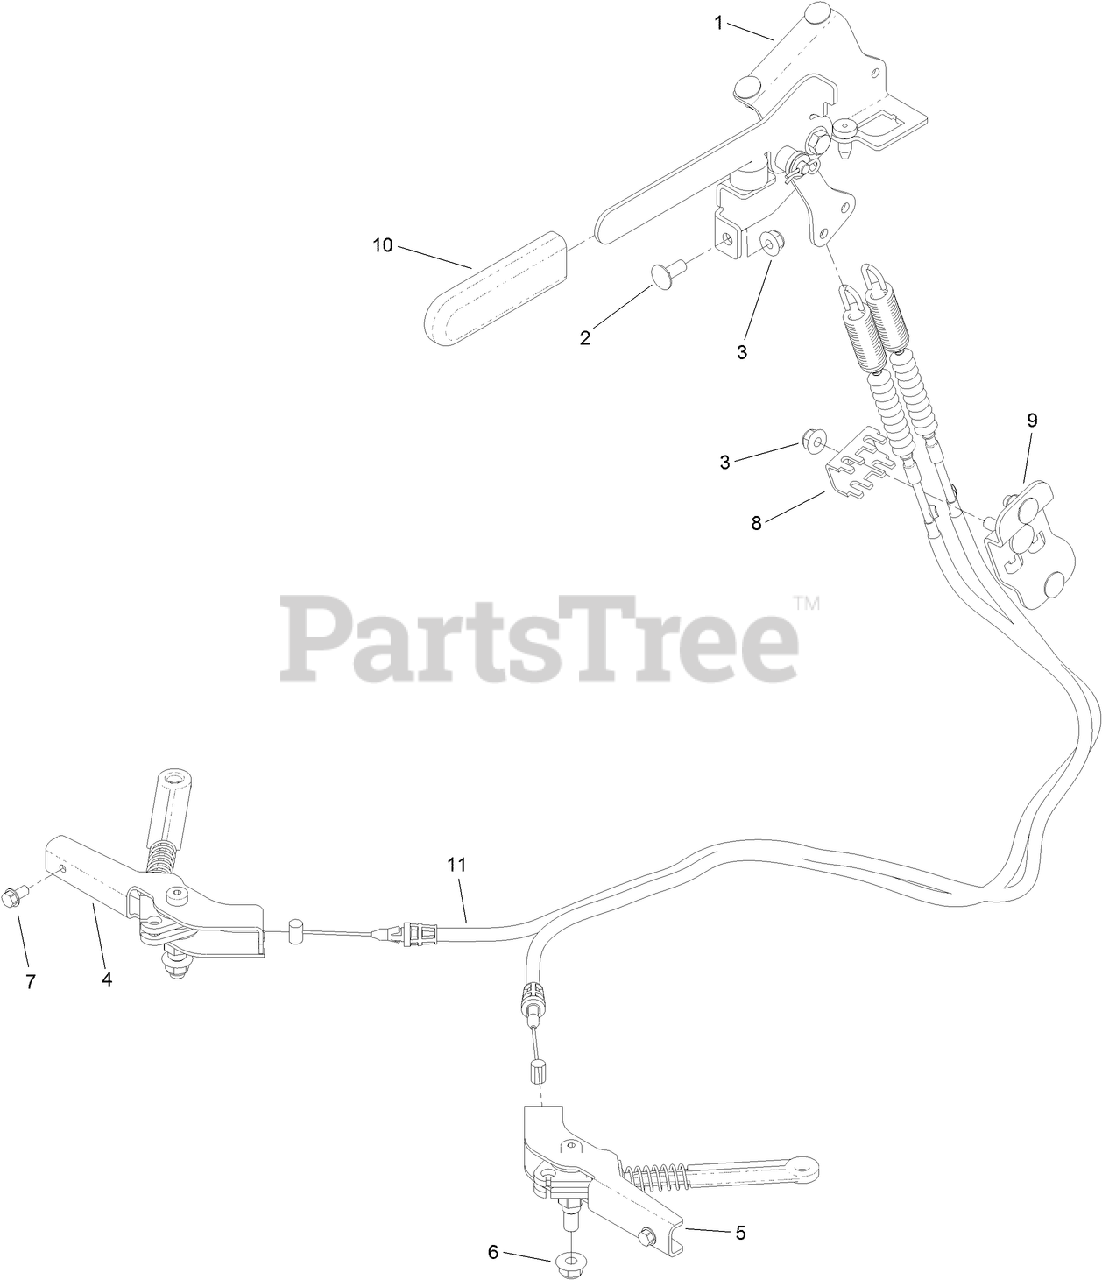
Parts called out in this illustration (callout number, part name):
1	BRAKE HANDLE ASM
2	SCREW-CARR
3	NUT-HF, NI
4	RH BRAKE CALIPER ASM
5	LH BRAKE CALIPER ASM
6	NUT-HF, NI
7	SCREW-HWH
8	CLAMP-CABLE
9	MOUNT-CABLE, BRAKE
10	GRIP-LEVER
11	CABLE-BRAKE
